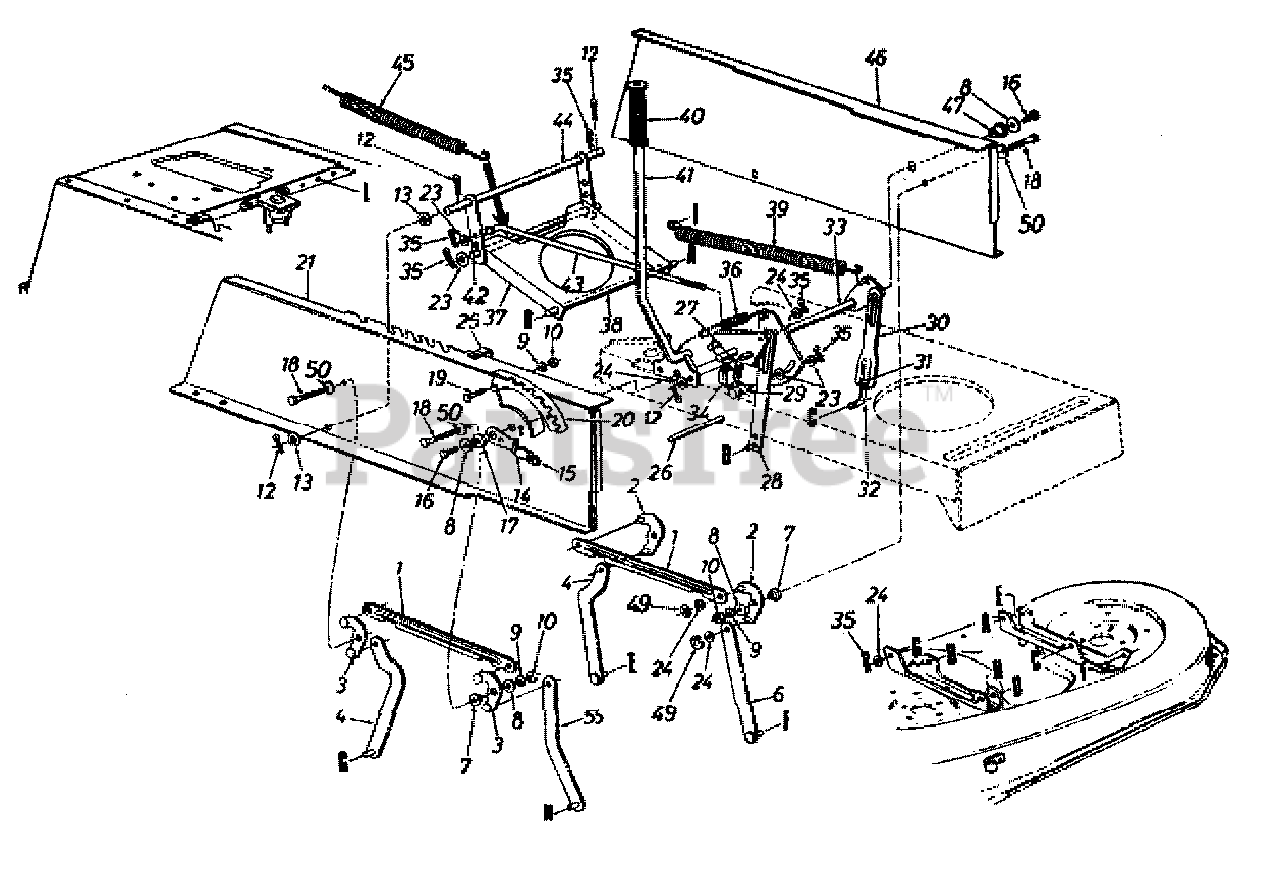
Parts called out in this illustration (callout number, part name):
3	Pivot Link Ass'y.-R.H.
7	Shld. Spacer .318" I.D.
8	Fl-Wash. .344" I.D. x 1.25" O.D. x .12
9	L-Wash. 5/16" I.D.
10	Hex Nut 5/16-18 Thd.-Gr. 5
12	Cotter Pin 1/8" Dia.
13	Fl-Wash. .635" I.D. x 1.0" O.D.
14	Deck Lift Stop
16	Hex Wash. TT-Tap Scr. 5/16-18 x .75" Lg.
17	Flange Brg. .63" I.D.
18	Hex Wash. Hd. Scr. 5/16-18 x .875" Lg.
19	Hex Bolt 5/16-18 x .75" Lg.
20	Index Brkt.
21	Upper Frame-R.H.
23	Fl-Wash. .385" I.D. x .87" O.D.
24	Fl-Wash. .531" I.D. x .93" O.D.
26	Running Board Rod
27	Hex Wash. Hd. Tap Scr.
31	Hex Nut 1/2-20 Thd. (Gr. 5)
32	Lift Link Adjuster
35	Inter. Cotter Pin 3/8" Dia.
36	Extension Spring
39	Extension Spring
40	Grip (Lift Handle)
41	Deck Lift Handle Ass'y.
42	Shaft 3/8" Dia. x 9.34" Lg.
43	Disengagement Rod
44	Stabilizer Shaft Ass'y.
45	Extension Spring 7.58" Lg.
49	"E"-Ring
50	Bell-Wash. .325" I.D.
